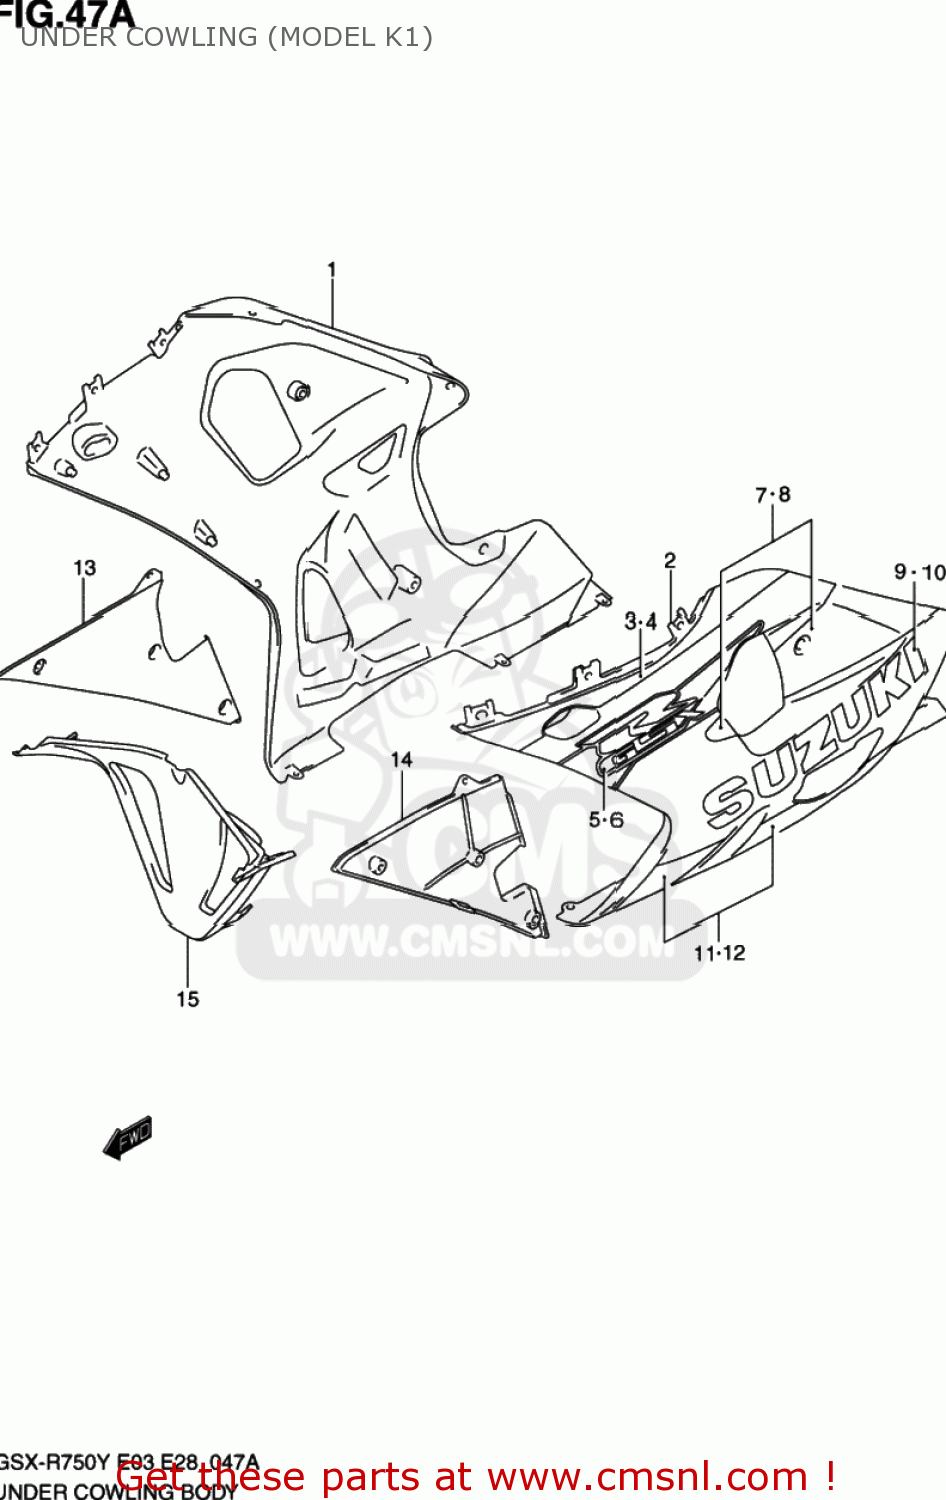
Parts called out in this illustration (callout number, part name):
1	COWLING ASSY,UNDER,R
2	COWLING ASSY,UNDER,L
3	TAPE,UNDER UPR,R
4	TAPE,UNDER UPR,L
5	TAPE(GSXR),UNDER,R
6	TAPE(GSXR),UNDER,L
7	TAPE SET,UNDER CTR,R
8	TAPE SET,UNDER CTR,L
9	EMBLEM SET,SUZUK,R
10	EMBLEM SET,SUZUK,L
11	TAPE SET,UNDER LWR,R
12	TAPE SET,UNDER LWR,L
13	COWLING,UNDER INNER,R
14	COWLING,UNDER INNER,L
15	COWLING,UNDER CTR
